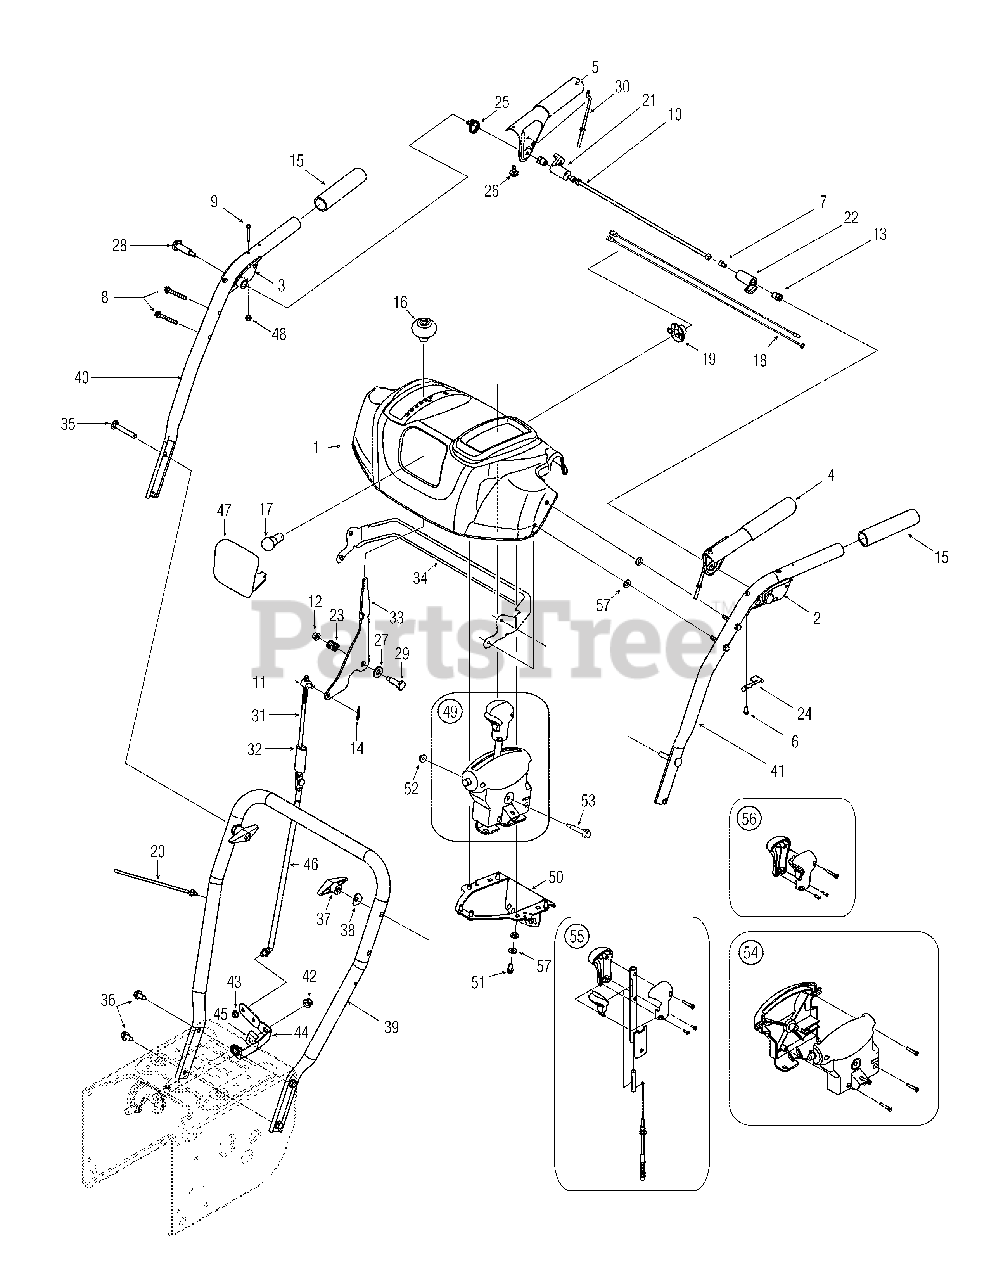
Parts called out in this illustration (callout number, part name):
1	Panel Assembly, L-Style, Black
1	Panel Assembly, L-Style, Gray
2	Handle Assembly, Clutch Lock, LH
3	Handle Assembly, Clutch Lock, RH
4	Handle Assembly, Engagement, LH
5	Handle Assembly, Engagement, RH
6	Screw, #8-16 x .50
7	Screw, 1/4-20 x .375
8	Screw, Self-tapping, 1/4-20 x 1.750
9	Screw, Machine, #10-24 x 1.375
10	Rod, Pivot
11	Ferrule, 5/16-18 x .312
12	Nut, Flange Lock, Nylon, 1/4-20
13	Nut, Shoulder, Hex, 1/4-20,
14	Pin, Cotter, .072 Dia. x 1.13
15	Grip, 1.0 ID x 5.0
16	Knob, Black
17	Lamp
18	Harness, Headlight
19	Socket, Lamp
20	Tie, Cable, 19 x 8.39", Tree Mount
21	Plate, Lock
22	Cam, Clutch Lock
23	Spring, Compression, .3 9 x .60 x .88
24	Spring, Clutch, Lock
25	Spring, Torsion, 0.8156 ID x .3038
26	Bumper, Rubber, .62 OD x .22
27	Washer, Flat, .3 85 x .870x .092
28	Screw, Shoulder, .4 37 x 1.345, 1/4-20
29	Screw, Shoulder, .3 74 Dia. x 1.05
30	Z-Fitting, Cable
31	Rod, Shift, .312 x 8.98 Upper
32	Connector Sleeve, Shift Rod
36	Screw, 5/16-12, 0.750
37	Wing Knob, 5/16-18
38	Washer, Saddle , 320 x .93 x .060
42	Nut, Flange Lock, Nylon, 5/16-18
43	Nut, Speed, .3125 Dia.
44	Spring Lever, Shift
45	Bracket, Shift Spacer
46	Shift Rod, Lower
47	Lens
48	Nut, Hex Lock, Nylon, #10-24, Gr2
49	Chute Control Assembly, 4-Way
51	Screw, 1/4-15 x .50
52	Nut, Hex Lock, 1/4-20
53	Bolt, Shoulder, 5/16 x 1.7, 1/4-20
54	Kit, Chute Control Housing
54	Joystick Control Complete, 4-Way
55	Kit, Lever Tube & Cable
56	Kit, 4-Way Knob
57	Washer, Flat, .25 x .630 x .051
